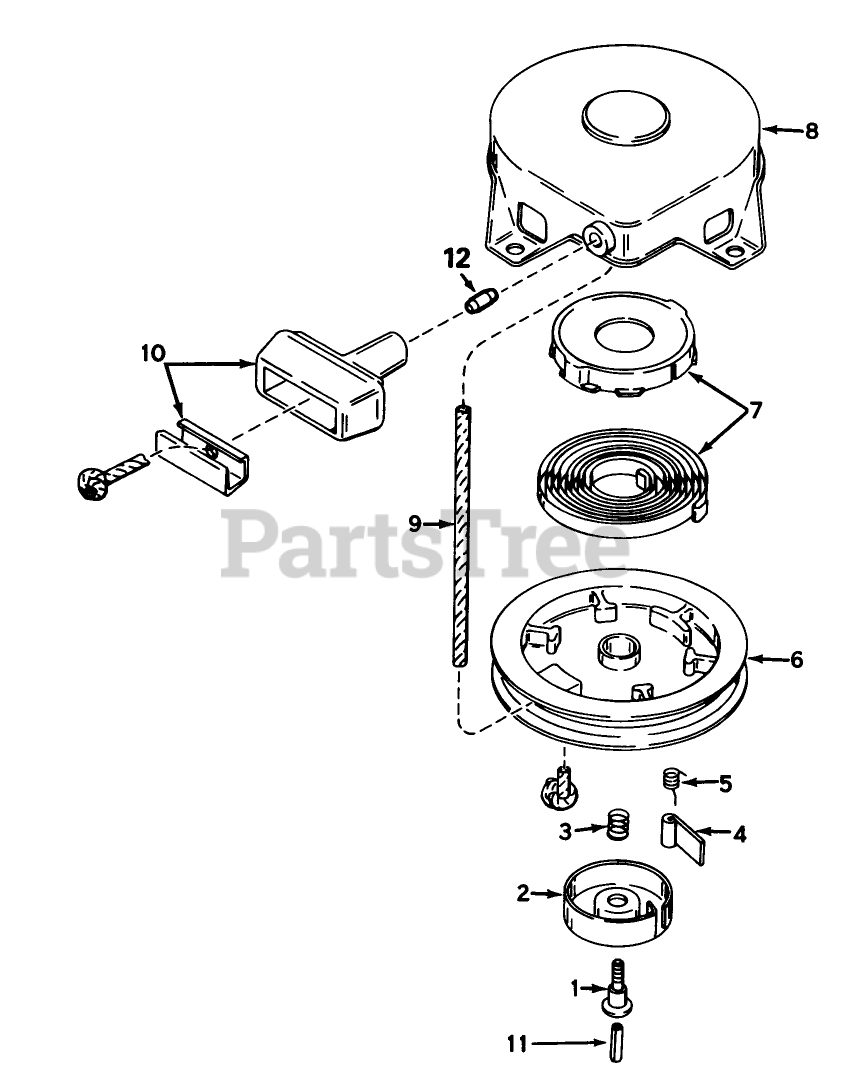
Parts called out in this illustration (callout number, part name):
1	Screw
2	Retainer
3	Spring-Brake
4	Dog-Starter
5	Spring-Dog
6	Pulley
7	Spring Keeper Assy
8	Housing Assy., Starter (Incl. Ref. #1)
9	Rope-Starter (98 cut to length)
10	Assy., Starter
11	Centering
12	Retainer-Starter Rope
